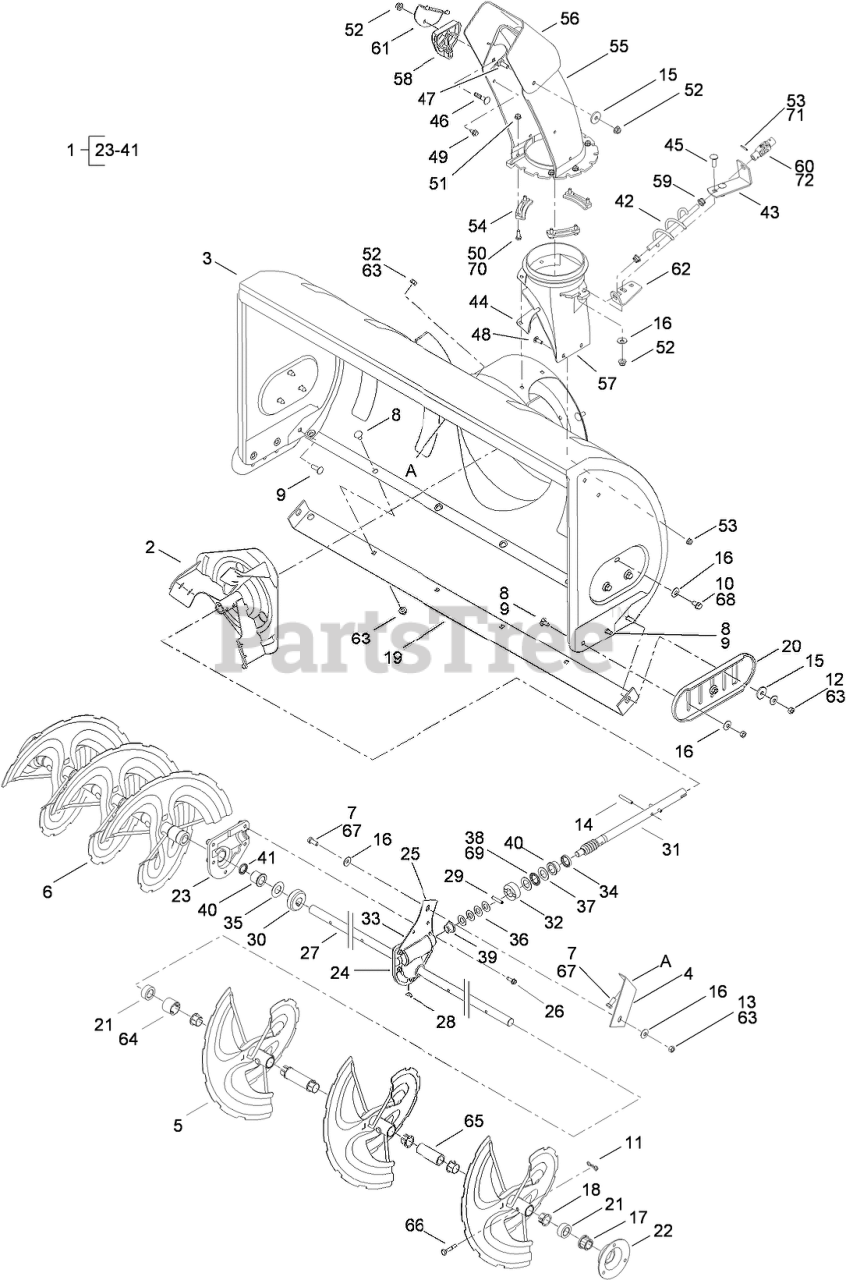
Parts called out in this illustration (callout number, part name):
1	AUGER GEARBOX ASM
2	IMPELLER ASM
3	HOUSING ASM
4	BRACKET-HOUSING, BRACE
5	LH SPIRAL AUGER ASM
6	RH SPIRAL AUGER ASM
7	SCREW-HH
8	BOLT-CARR
9	BOLT-CARR
10	BOLT-CARR
11	PIN-COTTER
12	NUT-HEX
13	NUT-HEX
14	PIN-ROLL
15	WASHER-FLAT
16	WASHER-BELL
17	BEARING-FLANGE
18	BEARING-FLANGE
19	BRACKET-PLATE, SKID
20	SHOE-SLIDE
21	SPACER
22	HOUSING-BEARING, HEX
23	HOUSING-REDUCER, RH
24	HOUSING-REDUCER, LH
25	PLATE-BRACE, HOUSING
26	SCREW-TAP
27	AXLE-SPIRAL
28	KEY-HI PRO
29	PIN-SPIROL, SPRING
30	GEAR-WORM, 20T
31	SHAFT-WORM
32	COLLAR-THRUST
33	PLUG-GREASE
34	SEAL-GREASE
35	WASHER-THRUST
36	WASHER-FLAT
37	WASHER-THRUST
38	BEARING-THRUST
39	BEARING-FLANGE
40	BEARING-FLANGE
41	SEAL-GREASE
42	CRANK CHUTE ASM
43	BRACKET-CHUTE
44	REINFORCEMENT-CHUTE
45	BOLT-CARR
46	BOLT-CARR
47	BOLT-CARR
48	BOLT-CARR
49	SCREW-HH
50	SCREW-HH
51	NUT-LOCK, FLANGE
52	NUT-LOCK, FLANGE
53	PIN-SPRING, SPIRAL
54	KEEPER-FLANGE, CHUTE
55	CHUTE-LOWER
56	CHUTE-UPPER
57	ADAPTER-CHUTE, DISCHARGE
58	GUIDE-CABLE
59	BEARING-BALL
60	JOINT BLOCK ASM
61	BRACKET-CABLE
62	BRACKET-CRANK, CHUTE
63	NUT-LOCK, FLANGE
64	SPACER
65	SLEEVE
66	PIN-SHEAR
68	SCREW-TAP
69	BEARING-THRUST
70	SCREW-HEX
71	PIN-SPIROL
72	JOINT BLOCK ASM
